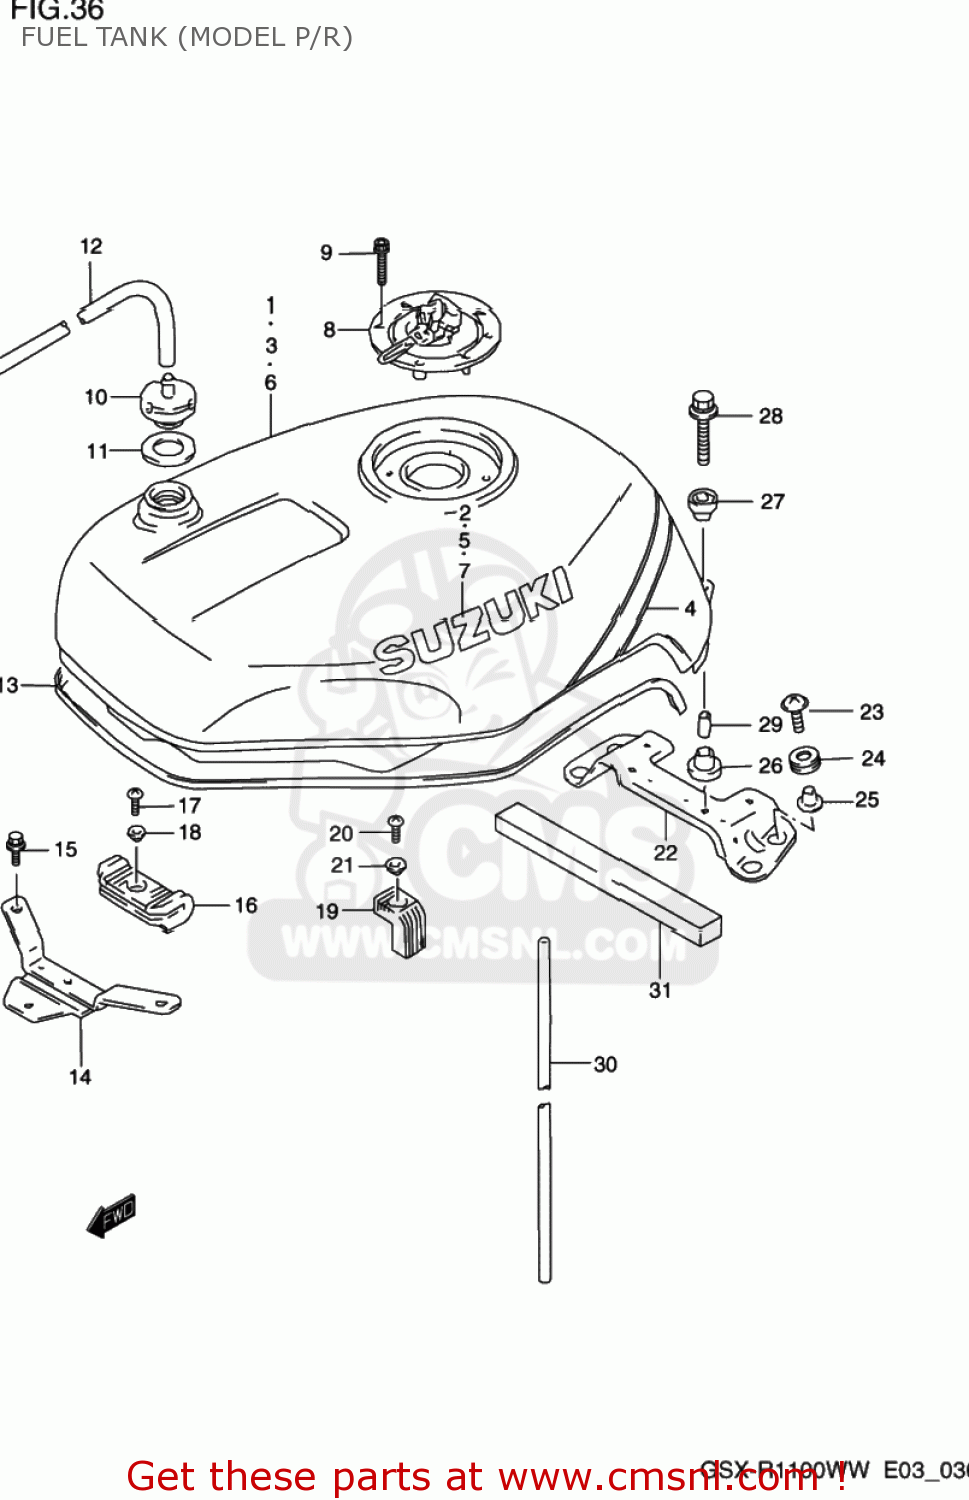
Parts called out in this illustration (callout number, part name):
1	TANK ASSEMBLY,FUEL
2	EMBLEM,FUEL TANK
3	TANK ASSEMBLY,FUEL
4	TAPE,FUEL TANK
5	EMBLEM,FUEL TANK
6	TANK ASSEMBLY,FUEL
7	EMBLEM,FUEL TANK
8	CAP SET,FUEL TANK
9	BOLT(5X20)
10	PLUG,FUEL TANK BREATHER
11	GASKET 27X40X2.5 (NAS)
12	HOSE(5X8.2X600)
13	MOLDING,FUEL TANK
14	BRACKET,FUEL TANK,FRONT
15	BOLT
16	CUSHION,FUEL TANK FR
17	SCREW
18	WASHER
19	CUSHION,TANK SIDE
20	SCREW
21	WASHER
22	BRACKET,FUEL TANK RR
23	SCREW(6X20)
24	CUSHION
25	WASHER
26	CUSHION
27	CUSHION
28	BOLT
29	SPACER
30	HOSE(7X10.2X2000)
31	CUSHION,AIR SEAL
